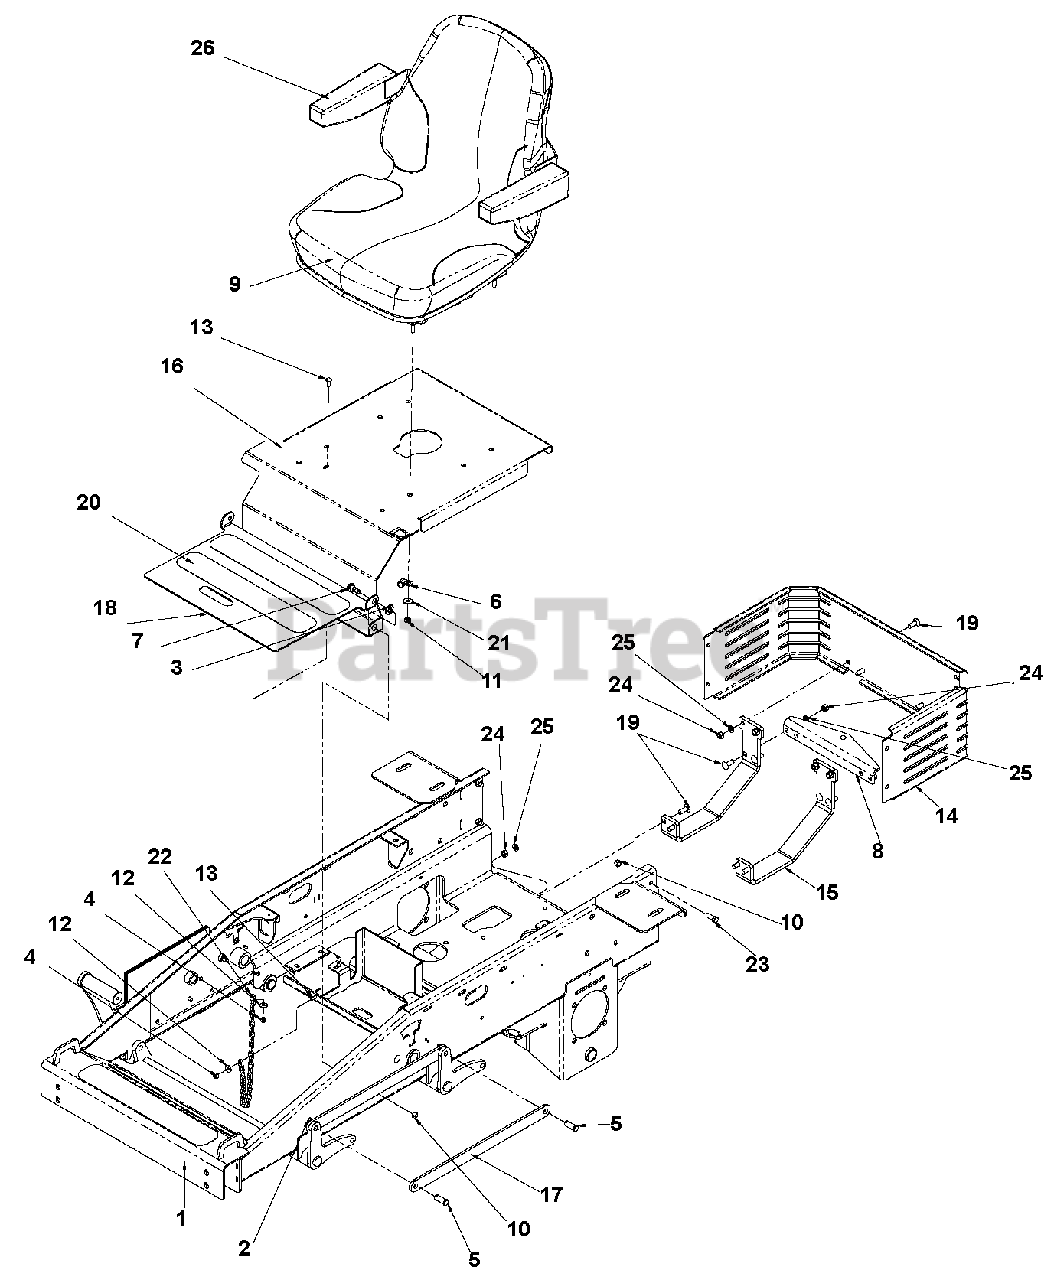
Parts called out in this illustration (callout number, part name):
1	Weldment, Frame
2	Ring, Rue .500 x .062 x 1.420
3	Washer, .510 x 1.00 x .068 Nylon
4	Locknut, 1/4-20 Nyloc
5	Pin, Cleavis .500 x 1.25 x 1.02
6	P-Clip, .500 Insulated
7	Bolt, 1/2 x 1.00 x 3/8-16 SLD 5
8	Plate, Hitch
9	Seat, Suspension - Light Grey
10	Locknut, 3/8-16 Crown
11	Locknut, 5/16-18 Crown
12	Washer, .250 Reg. Flat
13	Bolt, 1/4-20 x .750 Grade 5
14	Plate, Rear Guard
15	Brace. Bent Arm Hitch
16	Plate, Seat w/Decals
17	Plate, Arm Connector Link
18	Plate, Floor Pan
19	Bolt, 3/8-16 x 1.00 Grade 5
20	Tape, Traction 3.00 x 17.00
21	Washer, .313 Reg. Flat
22	Chain, .148 x 28 Links
23	Bolt, 3/8-16 x 1.00 Hex 5
24	Nut, 3/8-16 STD Hex Grade 5
25	Washer, .375 Med. Spring Lock
26	Kit, Arm Rest
